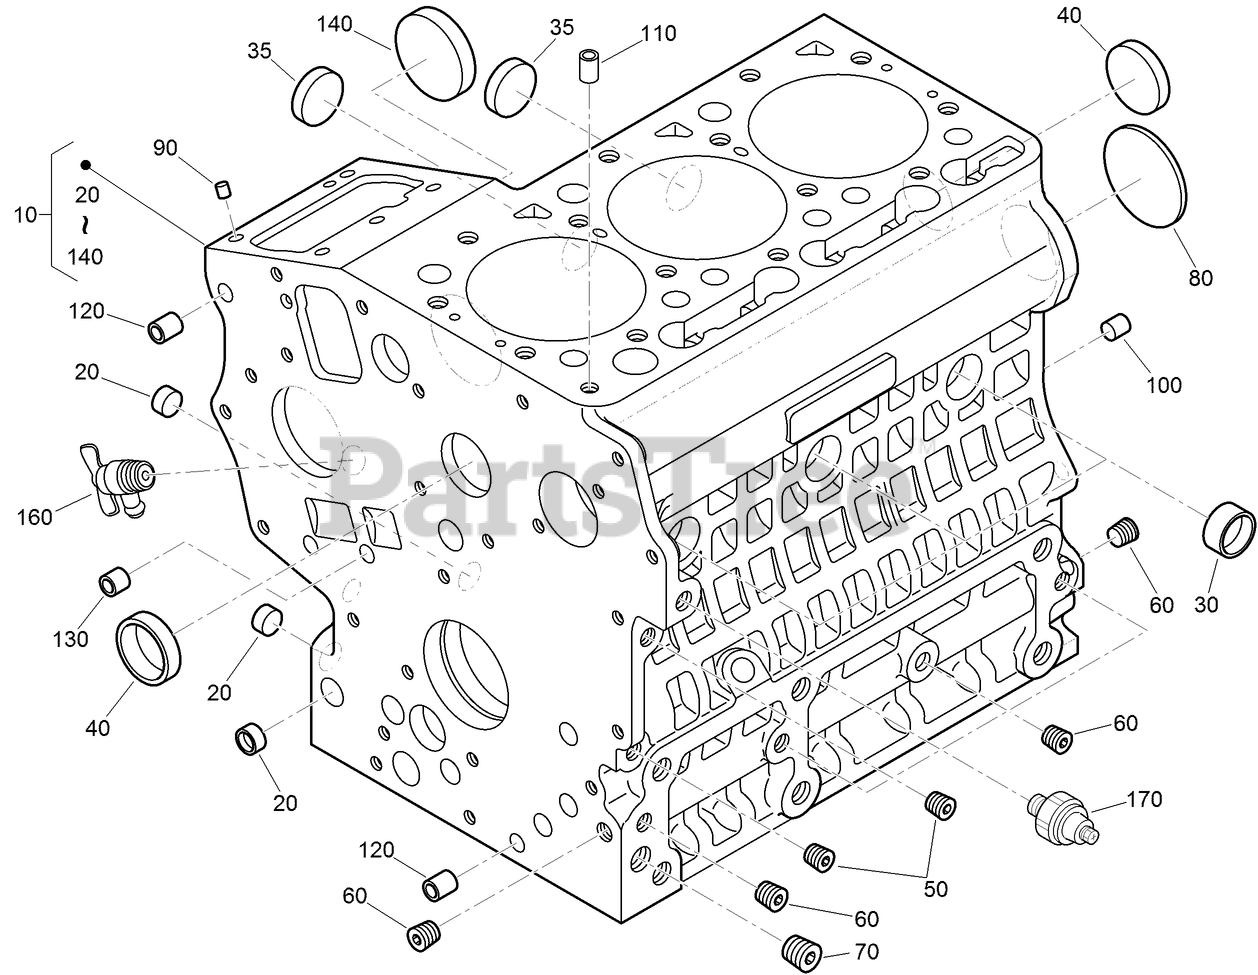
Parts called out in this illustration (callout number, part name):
10	CRANKCASE ASM
20	CAP-SEALING
30	CAP-SEALING
35	CAP-SEALING
40	CAP-SEALING
80	PLUG-EXPANSION
90	PIN-STRAIGHT
100	PIN-STRAIGHT
110	PIN-PIPE
120	PIN-PIPE
130	PIN-PIPE
140	COVER-FUEL, CAMSHAFT
160	DRAINCOCK ASM
170	THERMOSWITCH
